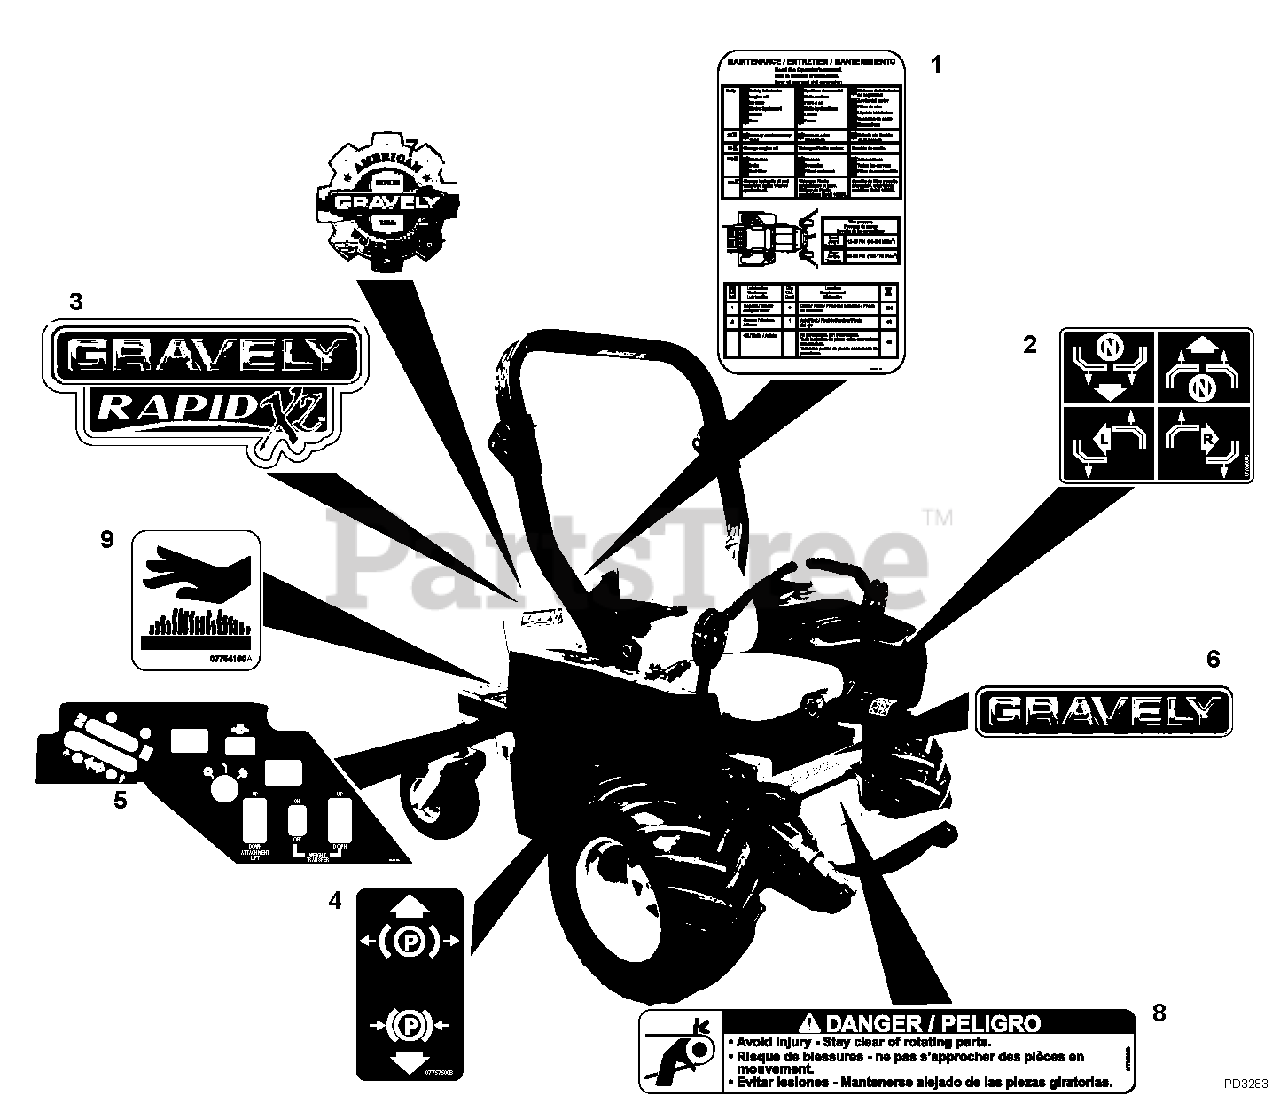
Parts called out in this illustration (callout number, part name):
1	Decal, Service Instructions Rapid XZ
2	Decal, Instructional Steering
3	Decal, Gravely Rapid XZ Hood
4	Decal, Parking Brake Lever
5	Decal, Control Panel Rapid XZ
6	Decal, 9.5" Gravely Logo
7	Decal, American Heritage
8	Decal, Danger
9	Decal, Hot Surface
